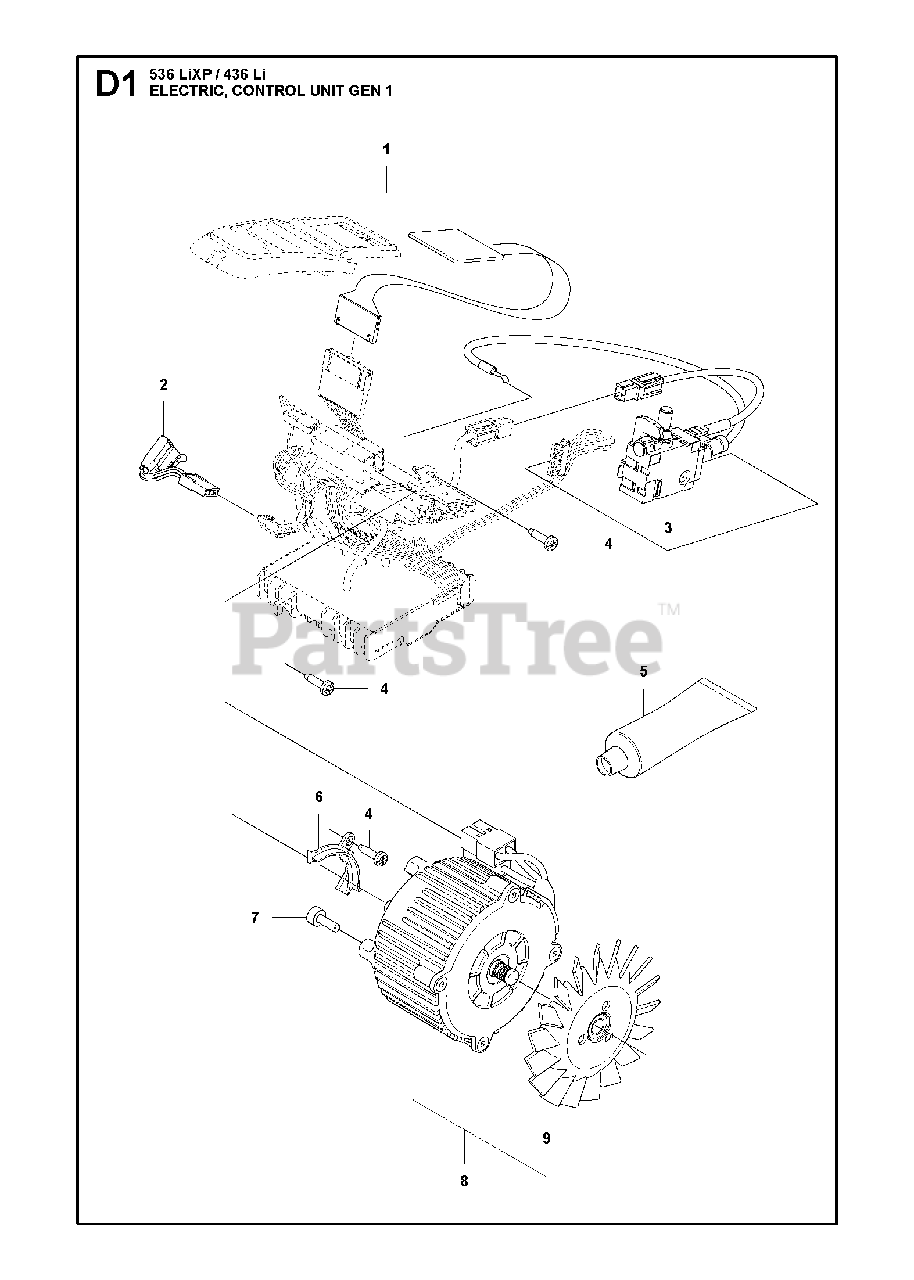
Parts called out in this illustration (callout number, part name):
2	WIRING ASSY
3	WIRING ASSY
5	GREASE TUBE Q8 RUYSDAEL WR2
8	MOTOR ASSY BLDC D70
